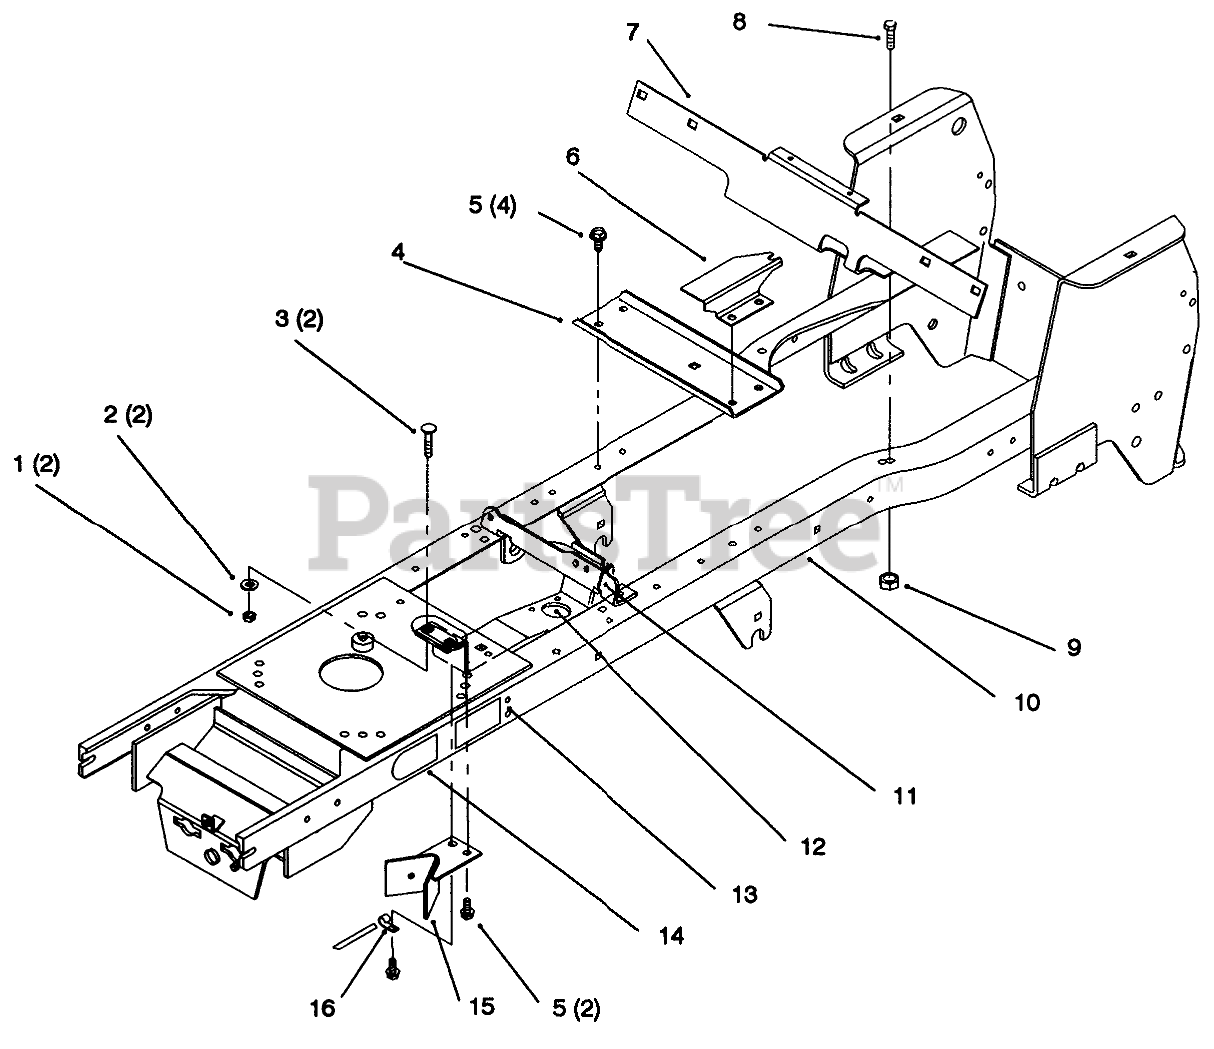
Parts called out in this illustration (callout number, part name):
1	NUT-LOCK, NI
2	WASHER-PLAIN
3	BOLT-CARR
4	Bracket-Idler
5	SCREW-HWHTF
6	Bracket-HOC
7	Support-Fender
8	SCREW-HH
9	NUT-LOCK, NI
10	Frame
11	TIE-CABLE
12	Bracket-Steering
14	DECAL-ATTACH A-MATIC
15	Stop-PTO
16	CLIP
